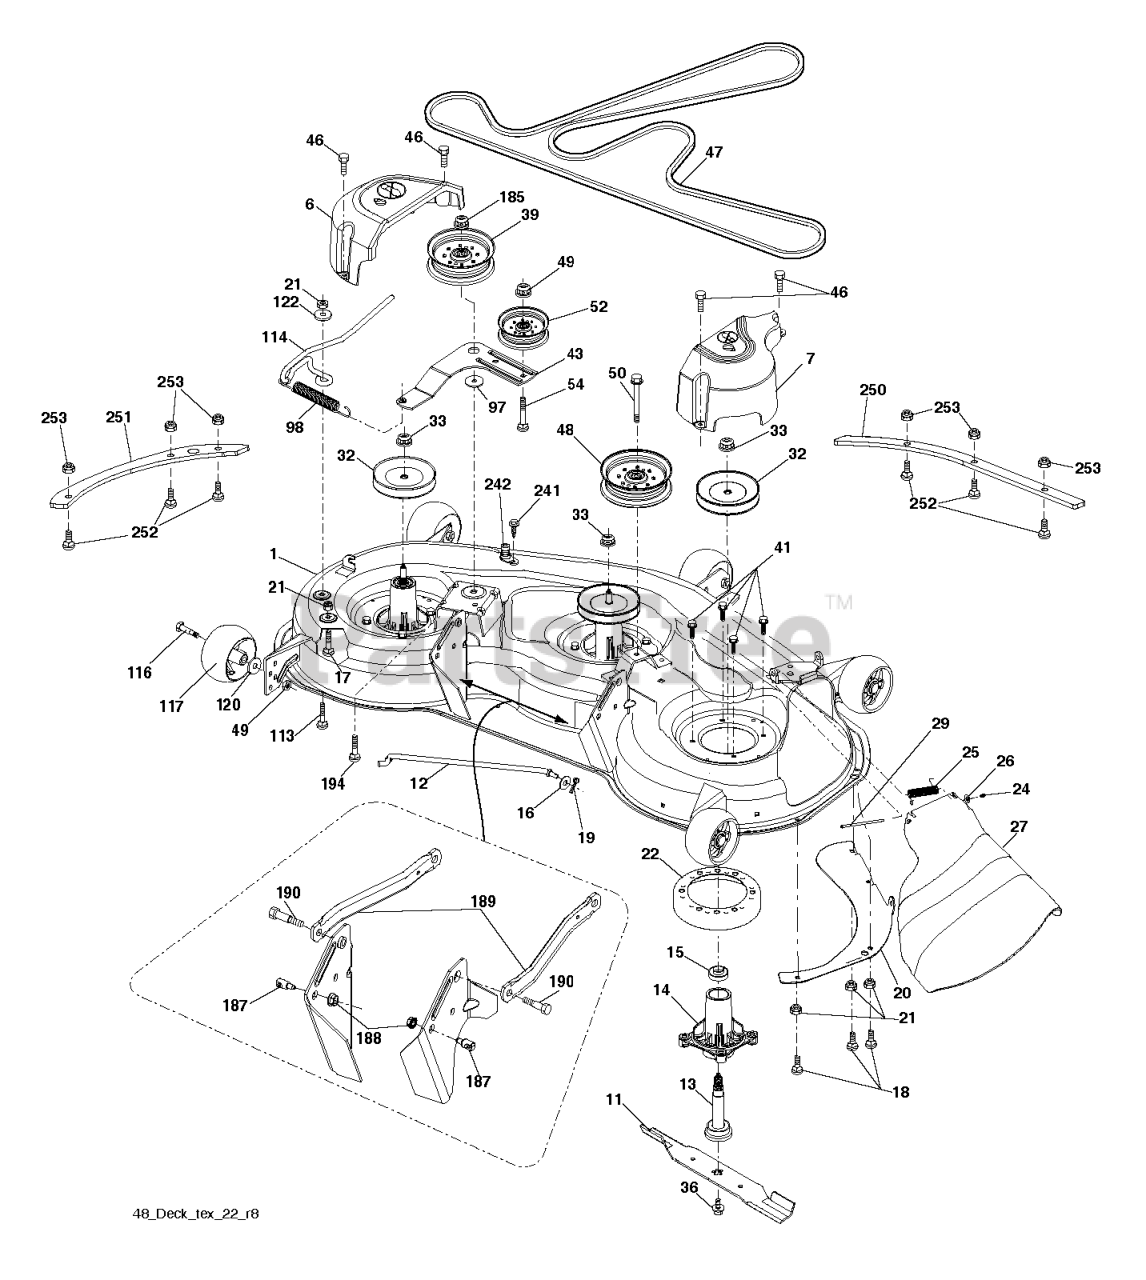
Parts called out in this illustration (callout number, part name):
1	DECK.SVC.48"
6	COVER.MANDREL.LH.48"(2 2)
7	SPACER.RETAINER
8	BOLT.WASHER.ASM.7/16-2
11	48" HI-LIFT BLADE
12	ROD.ANTI.SWAY.48/54"K4
13	SHAFT ASM MANDREL
14	RP.HOUSING.MANDREL.4PT.
16	WASHER
17	BOLT.CARR.5/16-18X5/8.SHORT
18	BOLT
19	PIN.COTTER.5/16.BOW TI
20	BAFFLE, VORTEX MWR
21	LOCKNUT
22	STRIPPER.MANDREL.ROUND.BLACK
24	CAP-SLEEVE LT
25	SPRING, TORSION
26	NUT PUSH M
27	DEFLECTOR SUBS TO 532 180655
29	ROD.HINGE
31	WASHER.SPACER.MANDREL
32	PULLEY/MANDREL
33	NUT.FLANGE.LOCK.TOP
39	RB PULLEY.IDLER.4.50/HUB SPEC
41	BOLT.HEX.WASHR.HED.313-18X1.19
43	ARM.IDLER
46	SCREW.1/4-20X5/8
47	BELT.DRIVE.DECK
48	PULLEY.IDLER.2006
49	NUT LOCK FLG 3/8-16 UNC
50	BOLT
52	PULLEY.IDLER.48"PRIMARY
54	BOLT.3/8-16X1.50
98	SPRING, DECK DRIVE
113	BOLT CRT
114	ROD.TENSION.RELIEF.TEX (2 2)
116	BOLT.SHOULDER.3/8-16X3-5/8.
117	RP WHEEL. GUAGE RALLY
120	WASHER
122	BUSHING.RELIEF.TENSION
185	NUT.LOCK.FLANGE.7/16
187	STUD.FASTNER.W/ANTI-ROTATE
188	NUT LOCK HEX FLANGE 5/16-18
189	ARM.SUSPENSION.MOWER
190	BOLT.SHOULDER
194	BOLT.HEX.WASHER.HEAD.7/16-24X
241	SCREW.TT.#10-32X.5.3/8.FLANGE
242	PORT.WASHOUT
